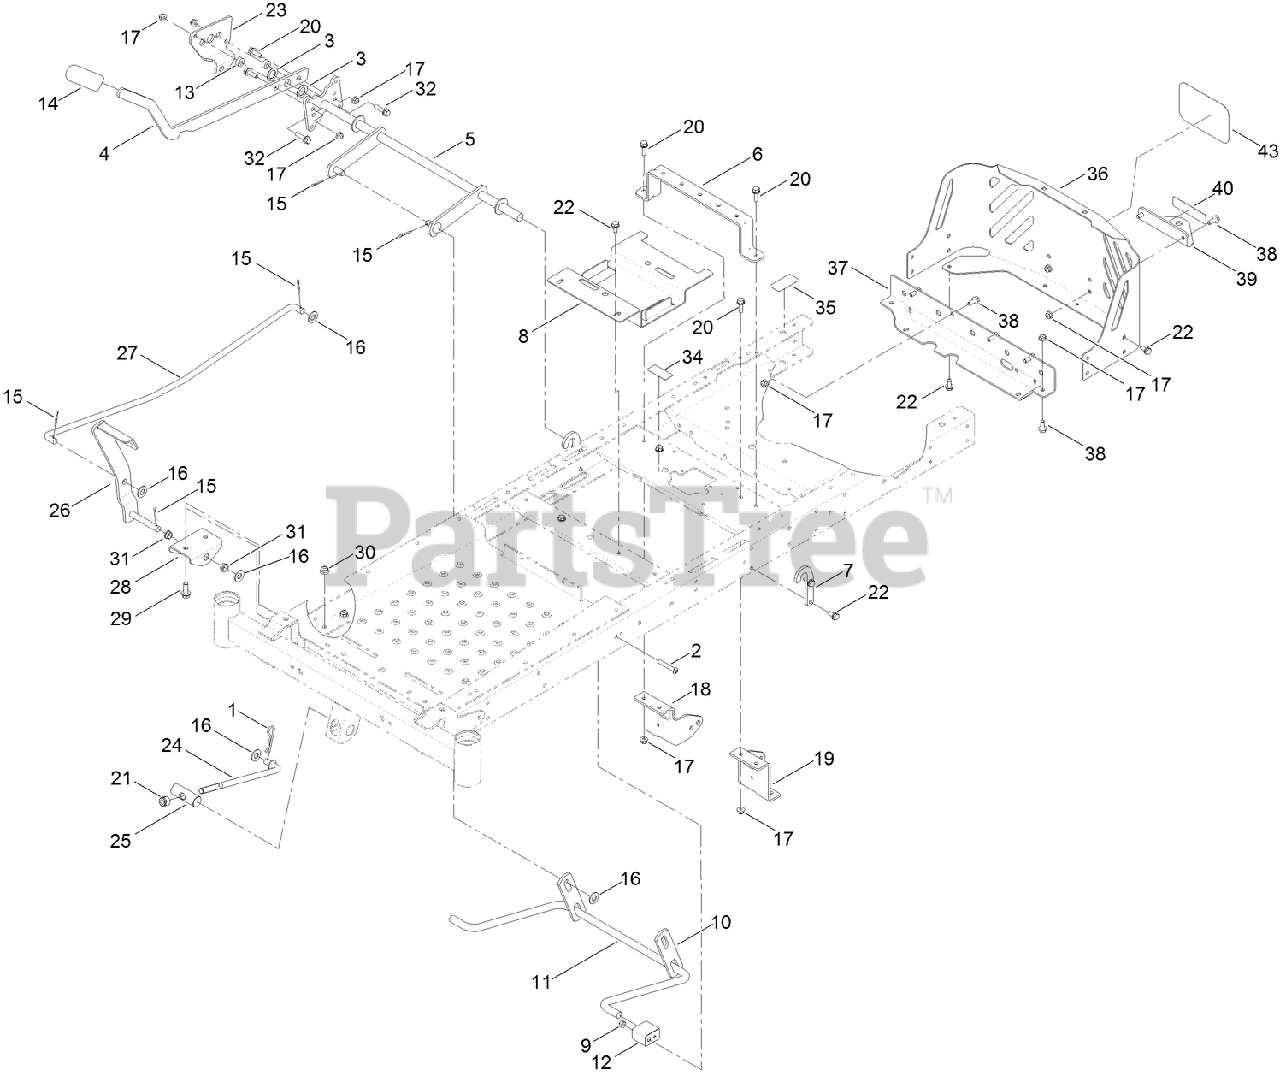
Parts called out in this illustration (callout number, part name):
1	PIN-COTTER
2	SCREW-HSBH
3	WASHER-THRUST
4	LEVER-LIFT
5	LIFT-DECK, NARROW
6	BRACE-SEAT, REAR (NARROW)
7	BRACKET-LIFT
8	BRACKET-BATTERY
9	NUT-LOCK, NI
10	LINK-LIFT
11	ARM-LIFT, REAR
12	BLOCK-PIVOT
13	SPACER
14	GRIP-LEVER
15	PIN-COTTER
16	WASHER-FLAT
17	NUT-HF, NI
18	MOUNT-HYDRO, FRONT (RH)
19	MOUNT-HYDRO, FRONT (LH)
20	SCREW-HHF
21	NUT-HEX
22	SCREW-HWHTF
23	PLATE-FOOTLIFT
24	ROD-MOUNT, DECK
25	PIN-PIVOT
26	PEDAL ASM
27	ROD-FOOTLIFT
28	BRACKET-FOOTLIFT
29	SCREW-HHF
30	NUT-HF, NI
31	BUSHING-FLANGE
32	SCREW-HHF
34	DECAL-LOCATION, SERVICE DEALER
35	DECAL-BYPASS
36	GUARD-ENGINE, NARROW
37	CROSSMEMBER-REAR, NARROW
38	SCREW-HHF
39	BRACKET-HITCH
43	DECAL
